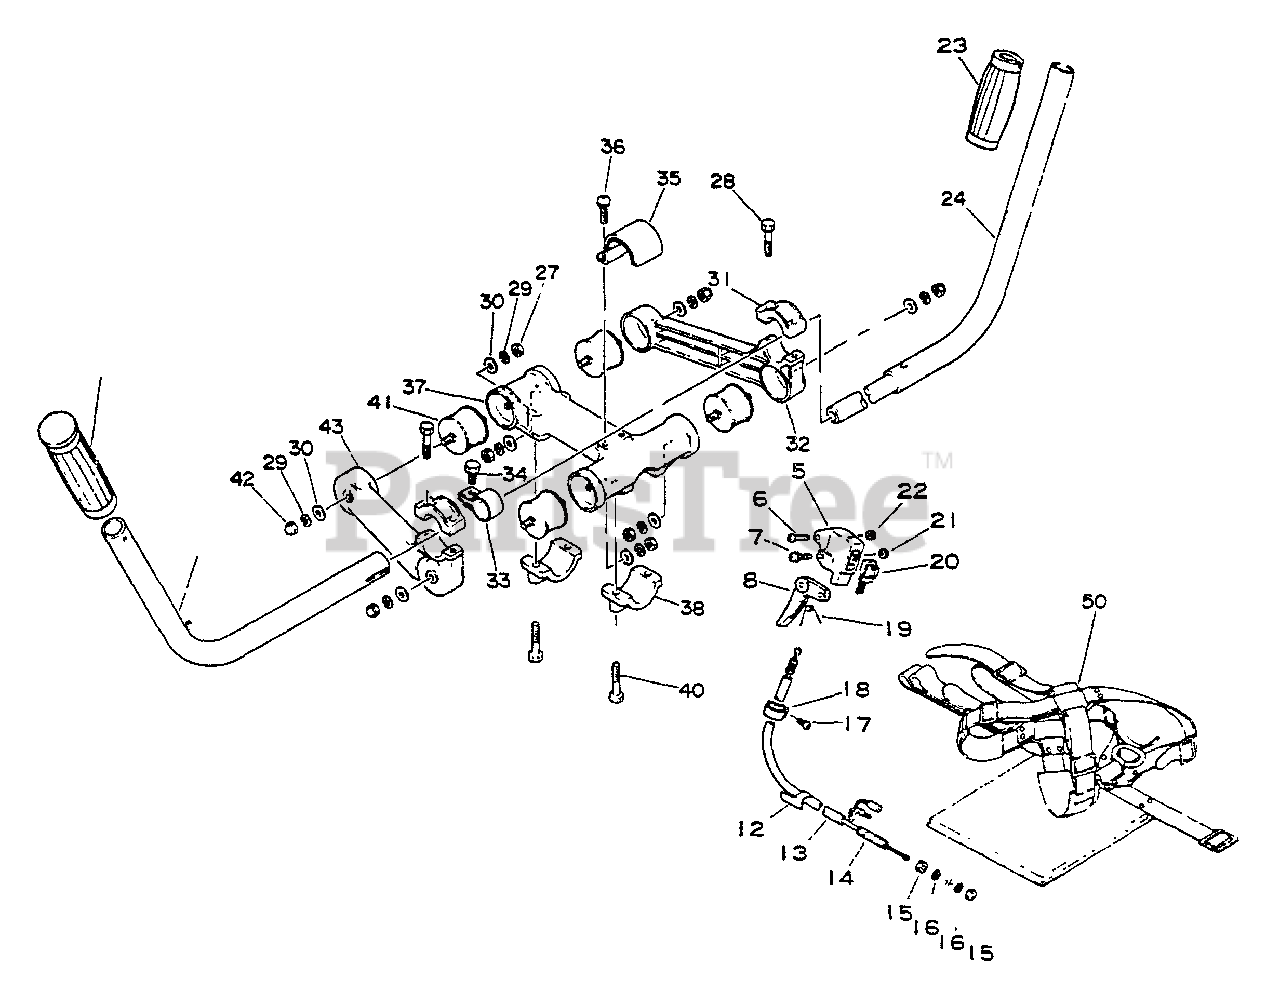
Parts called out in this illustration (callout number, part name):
5	BRACKET, THROTTLE
7	SCREW 5×30
8	TRIGGER, THROTTLE
14	CABLE, THROTTLE
15	NUT, HEX M6
16	WASHER 6.5×11.5×0.8
17	SCREW 5×10
20	SWITCH, ON-OFF
21	NUT M5
22	LOCKNUT - 5
27	NUT M5
28	BOLT - 5×25
29	WASHER, SPRING 5
30	WASHER, FLAT 5.5×10×0.8
31	RETAINER
32	ARM, RETAINER - RIGHT
33	BAND
34	BOLT - 6×12
35	PLATE
36	SCREW 5×14
37	HOLDER, D.S. HOUSING
38	HOLDER
40	BOLT - 6×30
41	CUSHION
42	NUT - 5 -- CAP
43	ARM, HANDLE - LEFT
44	HANDLE, FRONT
45	GRIP, HANDLE
50	SHOULDER STRAP ASSY
